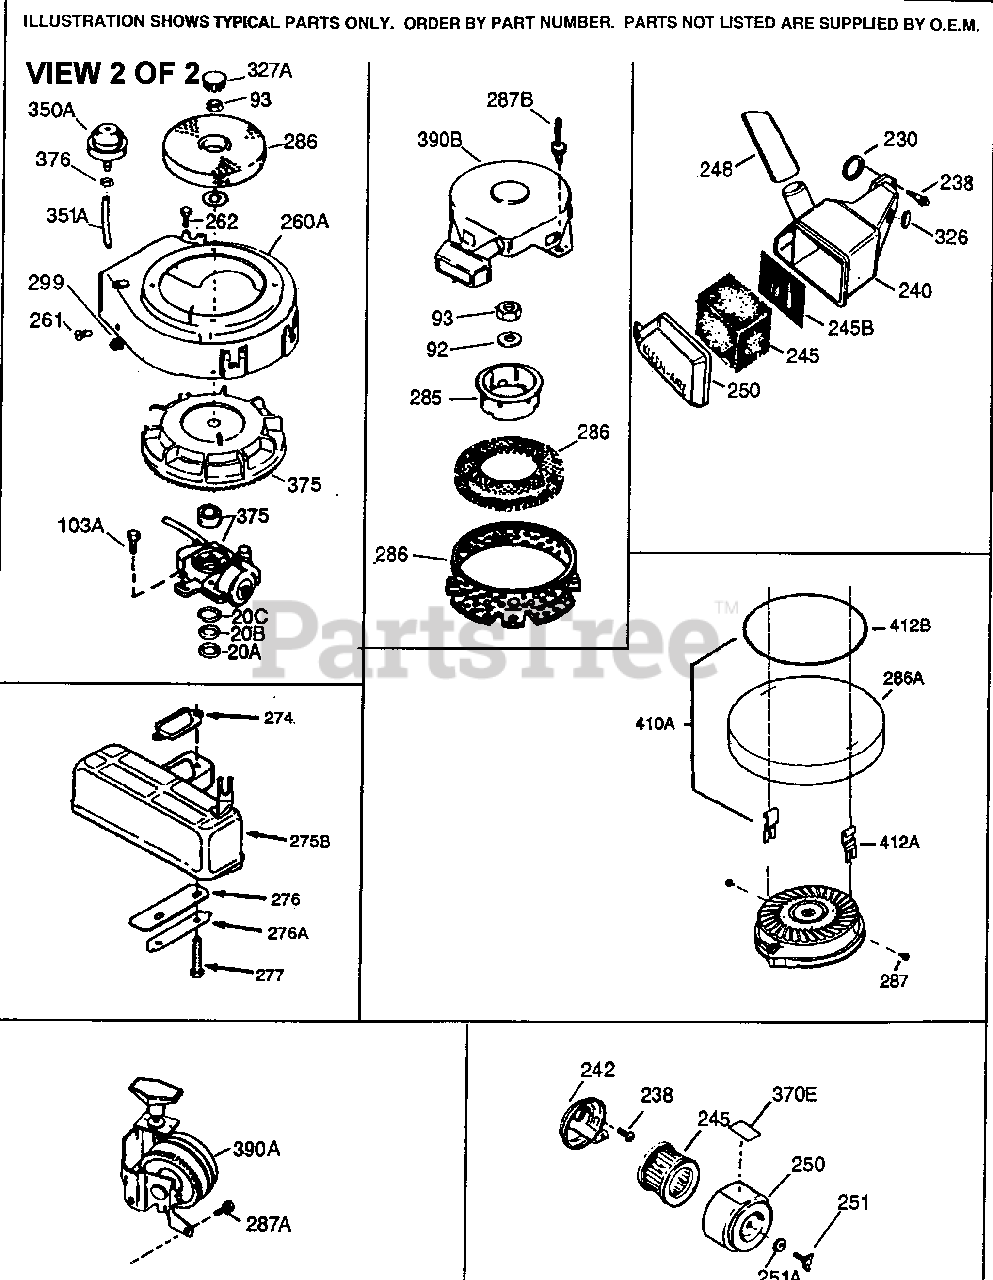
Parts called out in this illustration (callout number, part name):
27	Oil Seal
28	Oil Seal
28A	Oil Seal Retainer
28B	Oil Seal Retainer Spring
92	Belleville Washer
93	Flywheel Nut
103A	Screw, 1/4-20 x 3/4"
238	Screw, Torx T-25, 10-32 x 5/8"
240	Air Cleaner Body
245	Air Filter
245B	Air Filter
250	Air Cleaner Cover
260A	Blower Housing
261	Screw, 1/4-20 x 7/16"
274	Exhaust Gasket (.031" thick)
285	Starter Cup
286	Starter Screen
287B	Pop Rivet (3/16" dia.) Purchase local ly
299	Lock Nut, 1/4-20
350A	Primer Assy.
351A	Primer Line
375	Magneto The following magnetos are no t available as complete assemblies.Th e magneto number is shown for referen ce purposes only. Order component par ts in dividually as shown in parts li st. (Refer to Division 5, Section B, page 35 or Fiche 23B, G
390B	Rewind Starter NOTE: On some late pr oduction models, the top mounted rewi nd starter is riveted to the blower h ousing. If either the starter or blo wer housing needs replacement, the ot her may need the holes used for pop r iveting enlarged to ac
422	2-Cycle Oil with Fuel Stabilizer - 8 oz.
